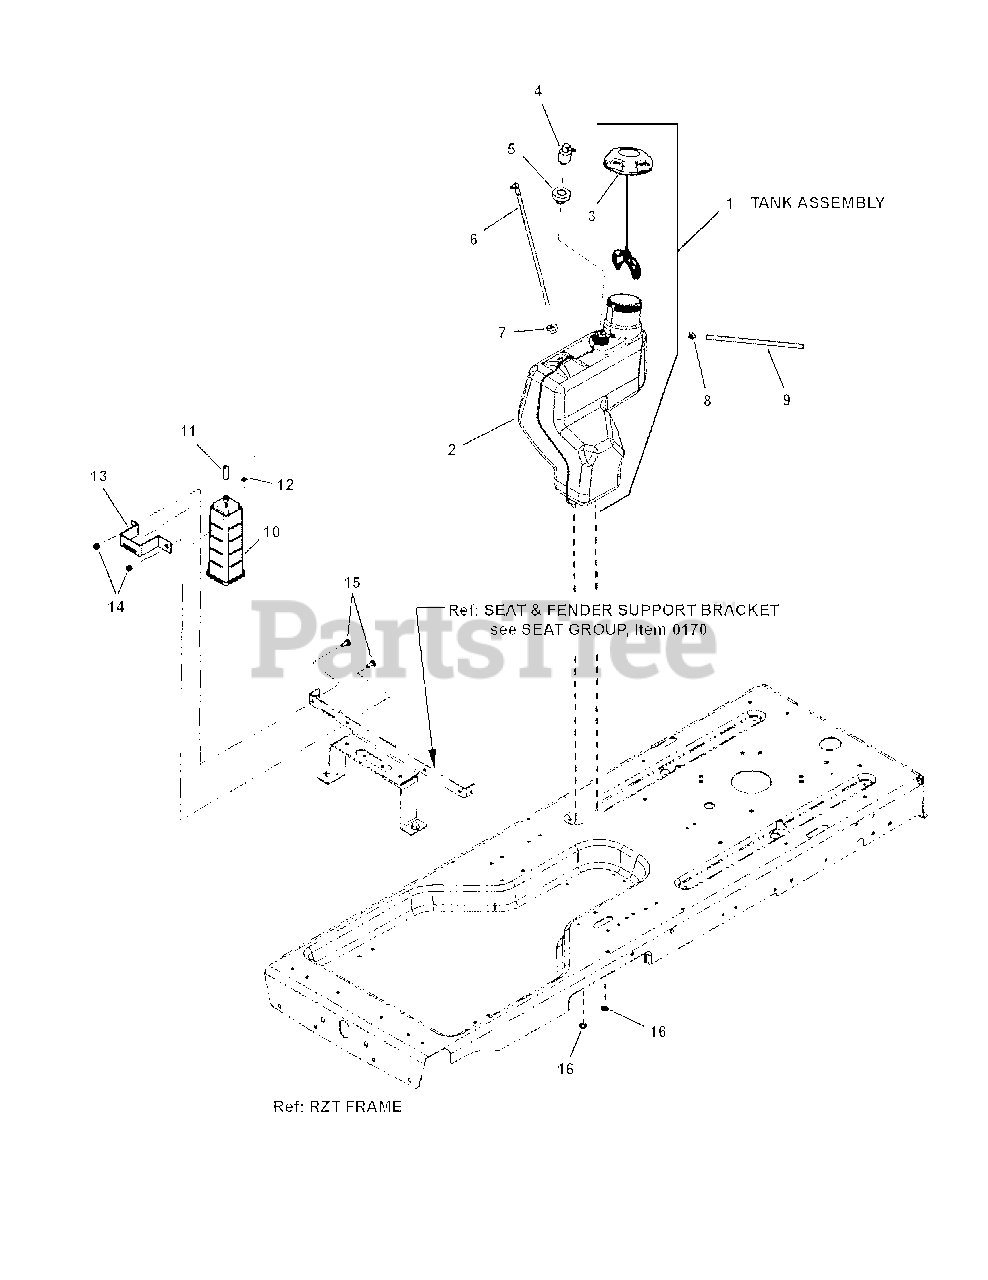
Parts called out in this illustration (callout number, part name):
1	ASSEMBLY, Tank, Emissions (incl. next 6 items)
3	CAP, Fuel, Emissions, 3-1/2", 12" Tether
4	ASSEMBLY, Remote Vent, No Valve
5	GROMMET
6	ASSEMBLY, Elbow, Pickup Tube
7	BUSHING, Fuel
8	CLAMP, Hose, Ctl
9	HOSE, Vapor
10	CANISTER, Vapor
11	CAP, Lift Rod
12	CLAMP, Hose
13	BRACKET, Vapor Canister
14	NUT, 1/4-20 Hex Nyloc, YZ
15	BOLT, 1/4-20 x 3/4" Round Head Short Square Neck Carriage, GR 5, YZ
16	RETAINER, 3/8" Bolt
